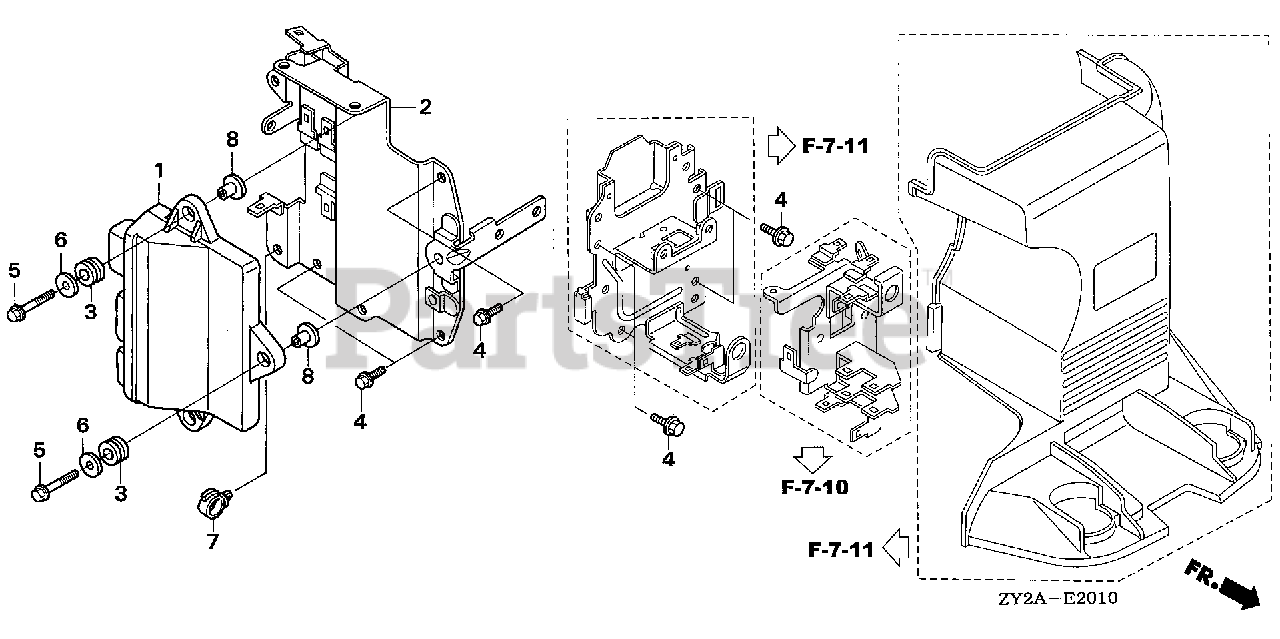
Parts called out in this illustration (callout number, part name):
1	CONTROL UNIT, ELECTRONIC
2	BRACKET, PCM
3	RUBBER, UNIT
4	BOLT, FLANGE (6X14) (CT200)
5	BOLT, FLANGE (6X28)
6	WASHER, PLAIN (22X6X1.6)
7	CLIP, WIRE HARNESS (25MM)
8	COLLAR, UNIT
